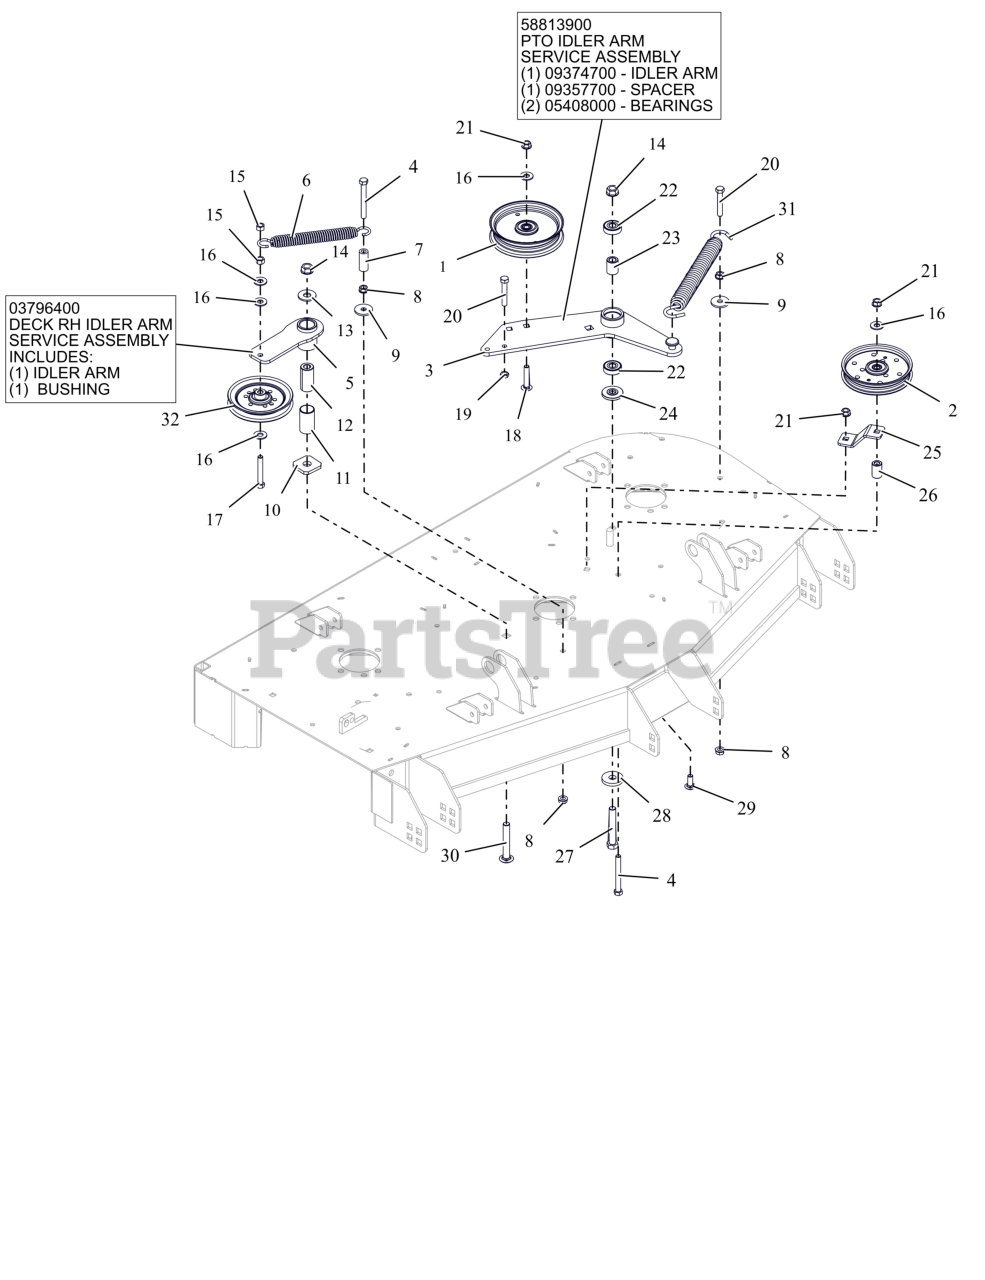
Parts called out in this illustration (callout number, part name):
1	IDLER- FLAT - 5.00" X .75"
2	IDLER- 5" FLANGED
3	PTO IDLER ARM
3	WLDMT, IDLER ARM PT660
4	BLT, HEX .38-16X3.25 G5 ZCC
5	ASM, IDLER ARM (DECK)
5	WMT, IDLER ARM - BLACK
6	SPRING- EXTENSION
7	HOSE, .38 X 1.65
8	NUT, SPNLK-FLG .38-16 G5 ZCC
9	WSHR,FLT .406X1.375X.135 ZCC
10	WSHR-FLT .640X1.75X.250
11	BSHG, 1.00X1.125X1.937
12	BSHG, SPCR .502X.997X2.03 PM
13	WSHR,FLT .563X1.375X.109 ZCC
14	NUT-LK-CTR-FLG .500-13 GG ZCC
15	NUT-LK-CTR .38-16 ZC120
16	WSHR,FLT .438X1.00X.083 ZCC
17	BLT, HEX .38-16X2.50 G5 ZCC
18	BLT,RHSSN.375-16X2.00 G5 ZCC
19	NUT-JAM .375-16 G2 ZCC
20	BLT,HEX .38-16X2.25 G5 ZCC
21	NUT-LK-CTR-FLG .375-16 GF ZCC
22	BRG-BALL .500X1.38X.437
23	SPACER .510 X .867 X 1.1485
24	SPACER, IDLER ARM
25	PTO FIXED IDLER MTG BRKT-ORG
26	BUSHING, SLV .380X.750X1.190
27	BLT,HEX .50-13X3.25 G5 ZCC
28	WSHR-FL-STL 0.557X1.625X0.25 ZCC
29	BLT,RHSSN .38-16X1.00 G5 ZCC
30	BTL,RHSSN .500-13 X 3.25 G5 ZCC
31	SPRING, EXTENSION
32	IDLER, V, 5.00X.38
